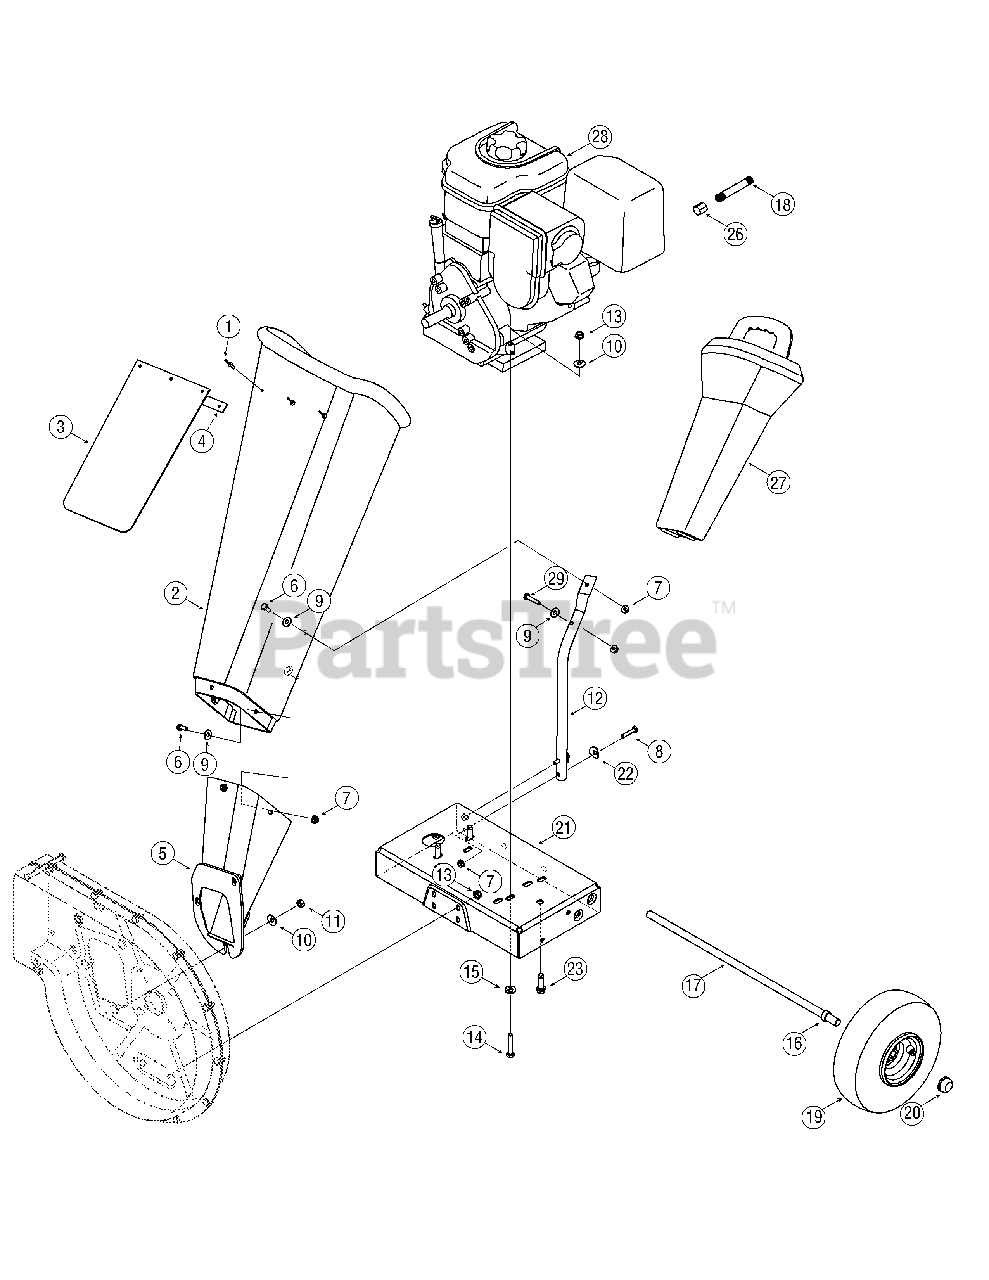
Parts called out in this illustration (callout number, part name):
1	Pop Rivet
2	Chipper Shredder Chute
3	Chute Flap
4	Chute Flap Strip
5	Chipper Chute Assembly
6	Hex Cap Screw 1/4 -20 x.620
7	Hex Lock Nut 1/4-20
8	Hex Cap Screw 1/4-20 x 1.25
9	Flat Washer .28 ID x .74 OD
10	Bell Washer .340 ID x .872 OD
11	Hex Nut 5/16-18
12	Support Brace
13	Hex Lock Nut 5/16-18
14	Hex Cap Screw 5/16-18 x 1.75
15	Bell Washer 5/16 x 1.0
16	Spacer
17	Axle Assembly
18	Pipe, Oil Drain
19	Wheel Complete, 10.0 x 4.0 Gray
20	Push Cap
22	Washer,.320 ID x.93 OD
23	Screw, 3/8-16 x 1.250
26	Oil Drain End Cap
27	Tamper
28	Replacement Engine 20T212-0835-F1
29	Hex Screw, 1/4-20 x 1.25
